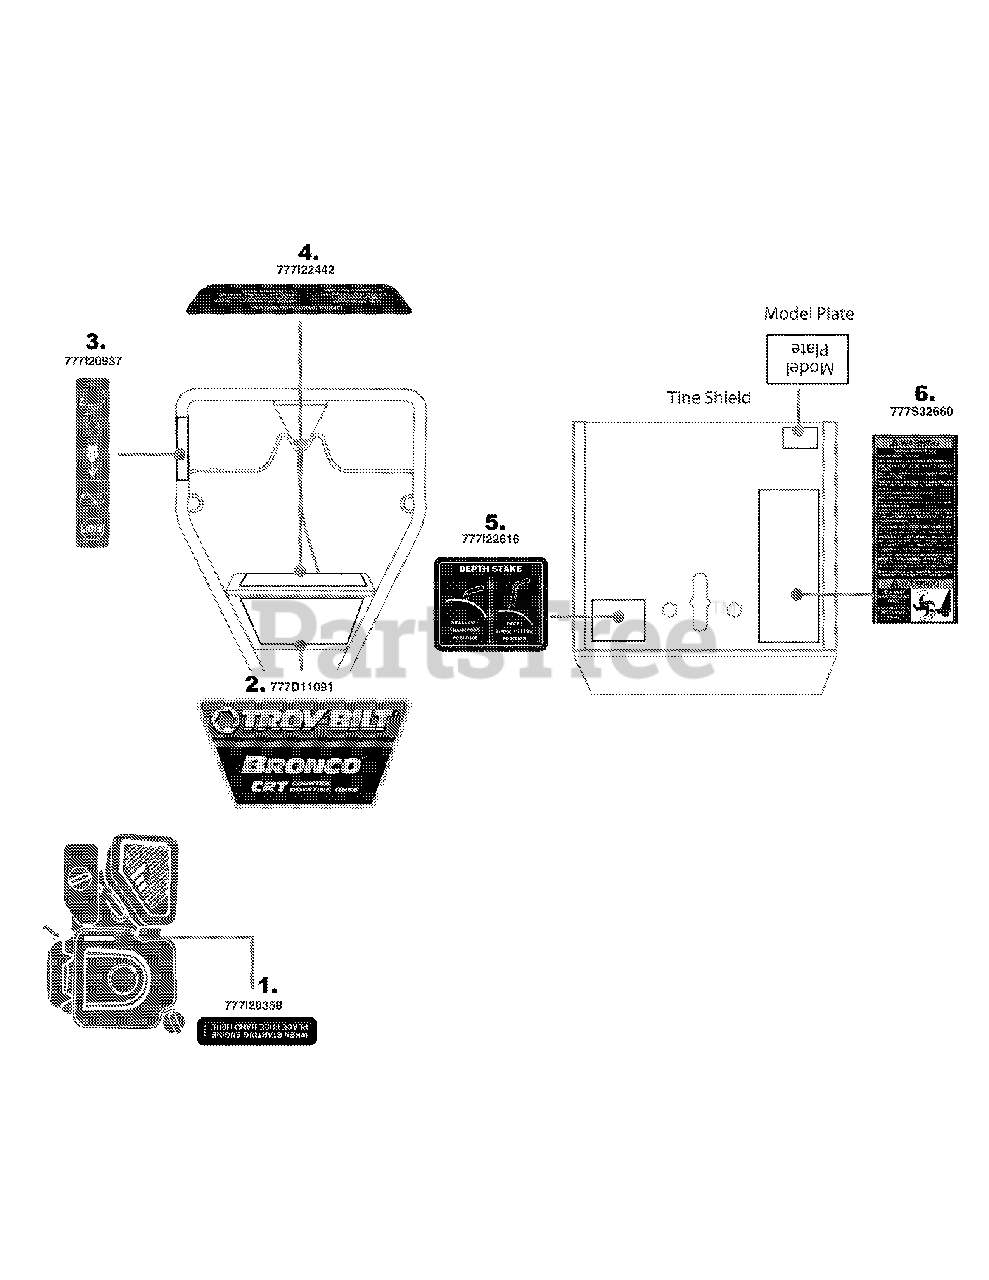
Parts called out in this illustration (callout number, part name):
1	LABEL-PLACE HAND HERE
2	LABEL-TILLER HANDLE BRONCO CRT
3	LABEL-BAIL CONTROL
4	LABEL-HANDLE PANLECRT
5	LABEL:TILLER TINE SHIELD DEPTH
6	LABEL:TILLER TINE SHIELD
